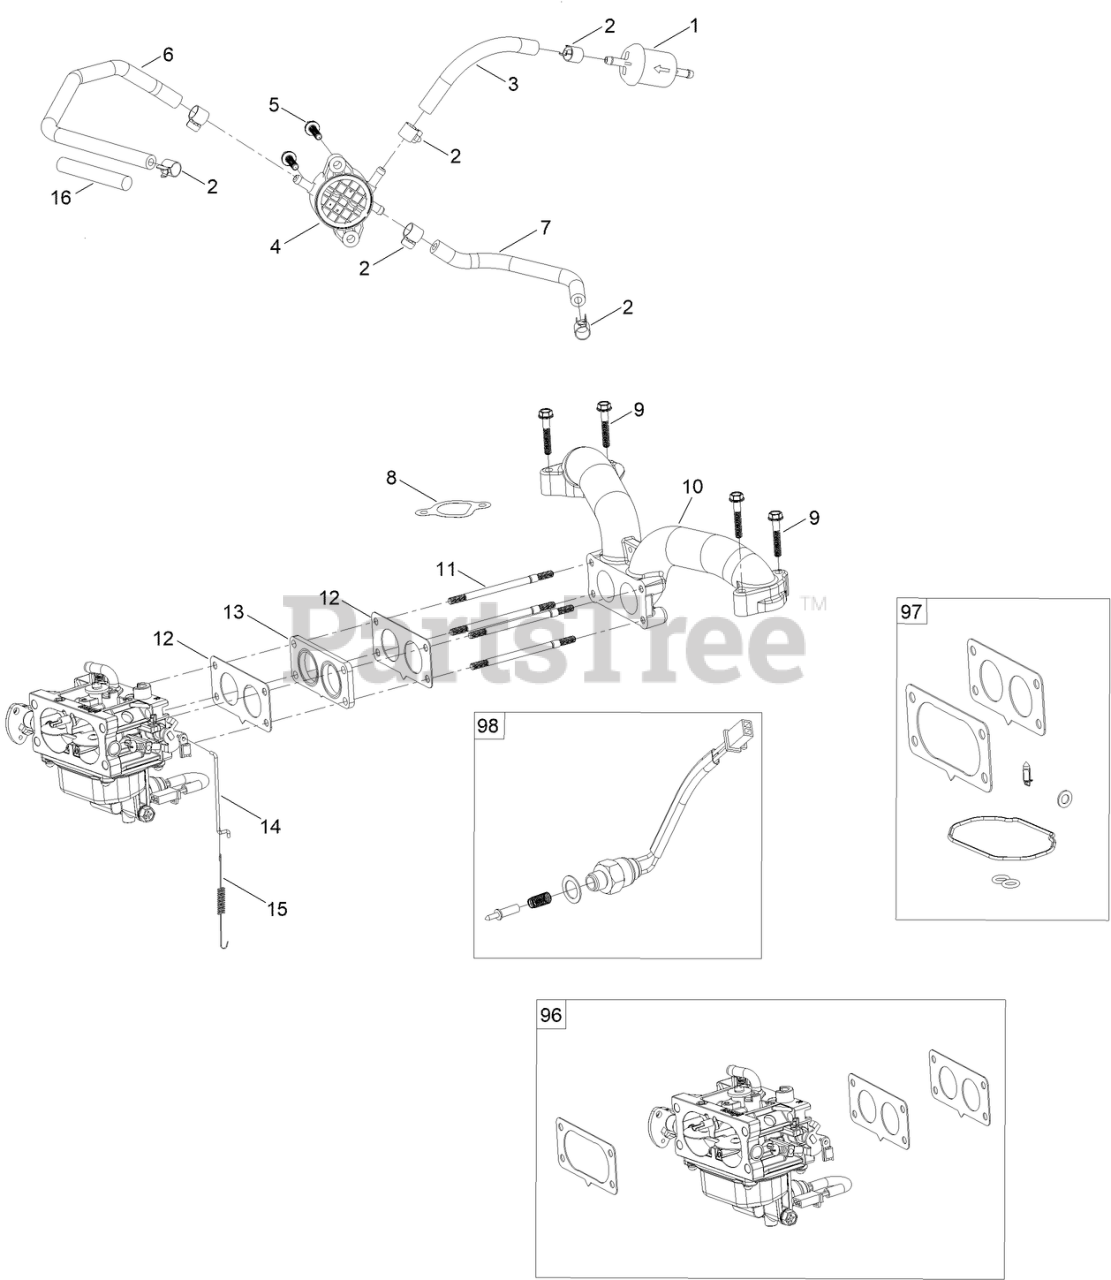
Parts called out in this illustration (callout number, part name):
1	FILTER-FUEL
2	CLAMP-FUEL HOSE
3	LINE-FUEL
4	PUMP-FUEL
5	SCREW-HHF
6	HOSE-FUEL
7	HOSE-FUEL
8	GASKET-INTAKE
9	SCREW-HHF
10	MANIFOLD-INTAKE
12	GASKET-CARBURETOR
13	INSULATOR-CARBURETOR
14	LINKAGE-THROTTLE
15	SPRING-RETURN, THROTTLE
16	SLEEVE-FUEL LINE PROTECTOR
96	CARBURETOR REPLACEMENT KIT ASM
97	CARBURETOR REPAIR KIT
98	SOLENOID KIT
